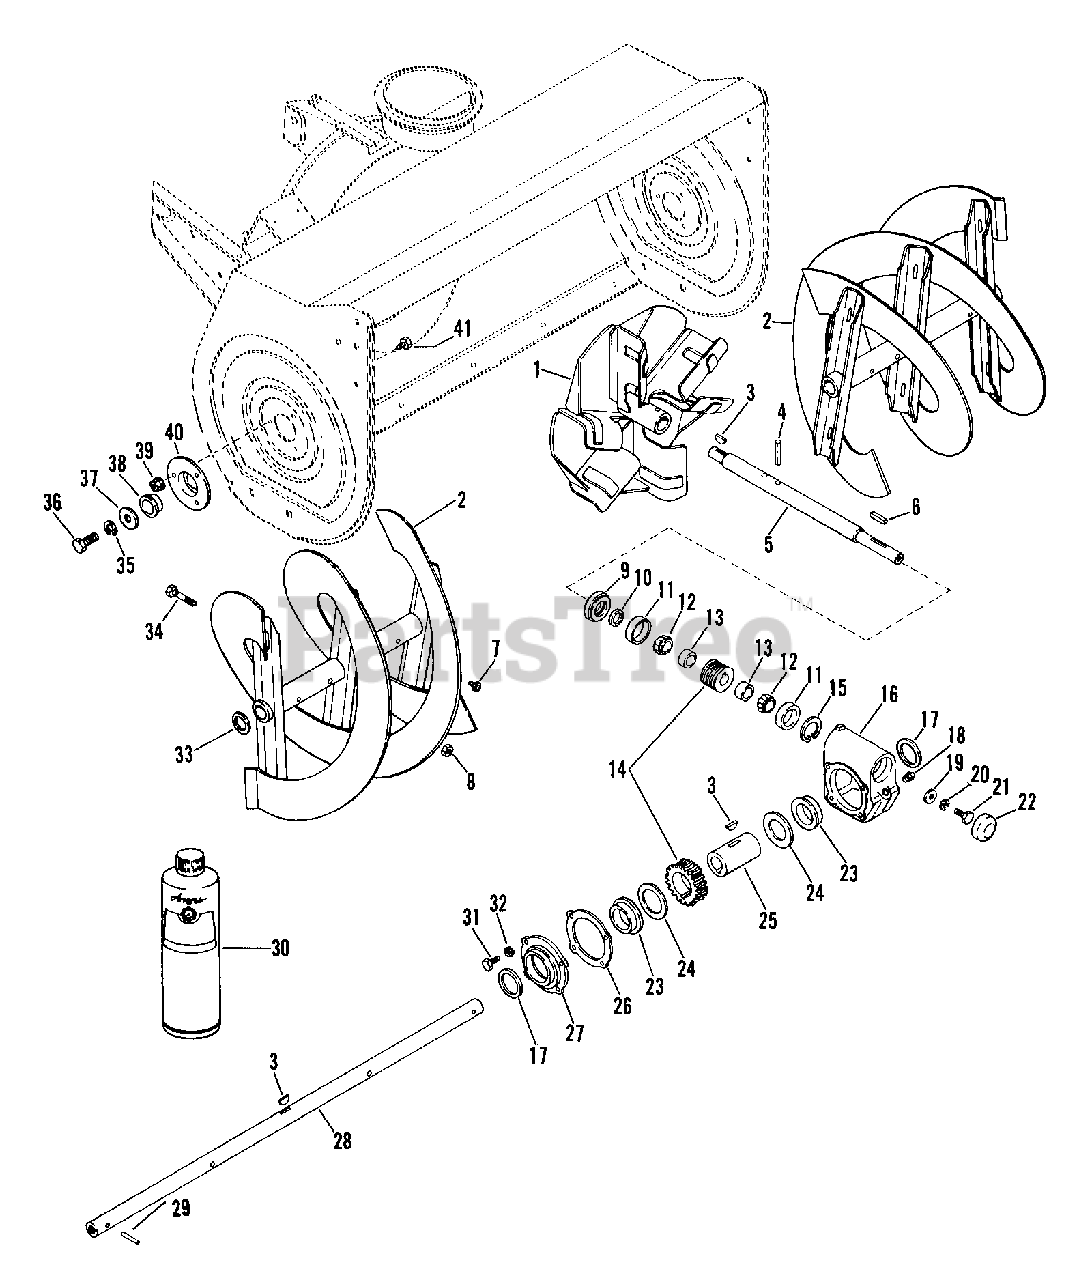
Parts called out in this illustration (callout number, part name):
1	FAN - 14"
2	RAKE, RIGHT-36"(1ID X 15.75OD)
2	RAKE, LEFT-36"(1"ID X 15.75OD)
3	KEY-WDRF .25X.875X.375 SAE A
4	PIN-ROLL .313X1.75
5	WORM SHAFT
6	KEY-SQ .188X1.0X.188 SAE 8630
7	SPIN DRIVE ZERK FITTING
8	NUT-LK .312-18 GR A PL
9	ADJUSTMENT PLUG - 1" SHAFT
10	SEAL 1.000X1.312X.150
11	BRG-CUP 1.781X.475
12	BRG-CONE .750X.61
13	BSHG, SPCR .755X1.12X.50 PM
14	WORM & GEAR SERVICE ASSEMBLY
15	RG-RTNG-INT 1.781X.062
16	GEAR CASE - 40" - CAST IRON
16	GEAR CASE - CAST IRON
17	SEAL 1.625X2.125X.250
18	PIPE PLUG
19	WSHR-FL-STL .328X1.0X.094
20	WSHR-LK .312X.097 PL HVY
21	BLT-HEX .31-18X.75 PL GR2
22	DUST CAP
23	BSHG-FLG .683X1.87X1.68X2.250
24	WSHR-FL-STL 1.625X2.500X.012
25	GEAR CASE SHAFT
27	GEAR CASE COVER
28	SHAFT, 36" RAKE - 1.00 DIA.
29	PIN-ROLL .188X1.50
30	ARIENS 16 OZ.BOTTLE OF L2 LUBE
31	BLT-HEX .25-20X.75 PL GR2
32	WSHR-LK-EXT. 250 ID
33	WSHR-FL-STL 1.010X1.505X.062PL
34	SHEAR BOLT SERVICE ASSEMBLY
35	WSHR-LK .500X.151 HVY PL
36	BLT-HEX .50-13X1.00 PL GR2
37	WSHR-FL-STL .511X1.441X.125 PL
38	BSHG-FLG 1.000X1.12X.62X1.50BR
39	NUT-LK-FLG .250-20 PL
40	BEARING SUPPORT
41	BLT-SERNK SL .25-20X.50 PL
